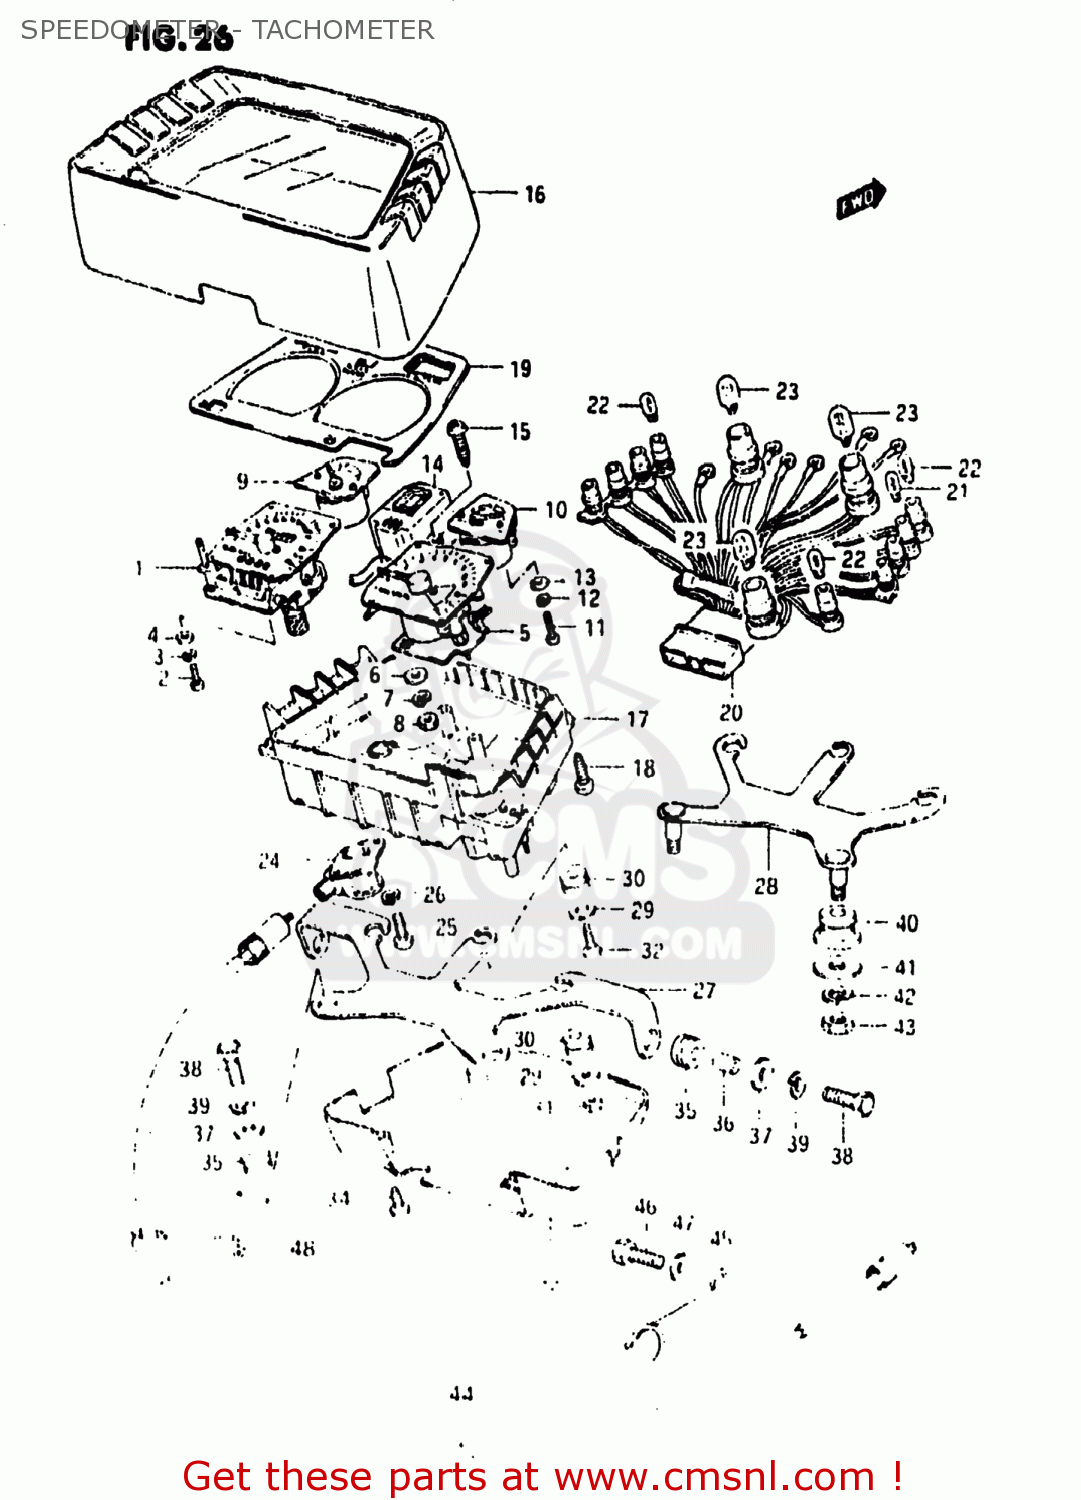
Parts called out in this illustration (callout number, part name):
1	METER,SPEEDOMETER (KM/MPH)
2	SCREW
3	LOCK WASHER
4	WASHER 3.3X8X0
5	TACHOMETER
6	WASHER
7	LOCK WASHER
8	NUT 4MM
9	METER,FUEL
10	METER,OIL TEMPERATURE
11	SCREW
12	LOCK WASHER
13	WASHER 3.3X8X0
14	INDICATOR ASSEMBLY,GEAR POSITION
15	SCREW
16	HOOD SET
17	CASE,METER
18	SCREW
19	PLATE,METER WINDOW
20	SOCKET UNIT,METER
21	BULB(12V1.7W,WB372,T7)
22	BULB(12V3W,WB371,T7)
23	BULB(12V3.4W,T10,BF175-01450A)
24	GEAR BOX,SPEEDOMETER
25	SCREWM4X0.7X10
26	LOCK WASHER
27	BRACKET,METER
28	BRACKET,METER
29	WASHER,COMBINATION METER
30	CUSHION
31	NUT 4MM
32	SCREW
33	COVER,METER
34	SCREW
35	CUSHION
36	SPACER (6.1X9X9)
37	WASHER
38	BOLT,M6X1X20
39	WASHER,LOCK
40	CUSHION,METER BRACKET
41	WASHER (8.5X20X1.6)
42	WASHER,LOCK,8.
43	NUT
44	CABLE ASSY,SPEEDOMETER
45	CLAMP,SPEEDOMETER CABLE
46	BOLT, UPPER
47	WASHER
48	GUIDE,METER CABLE
